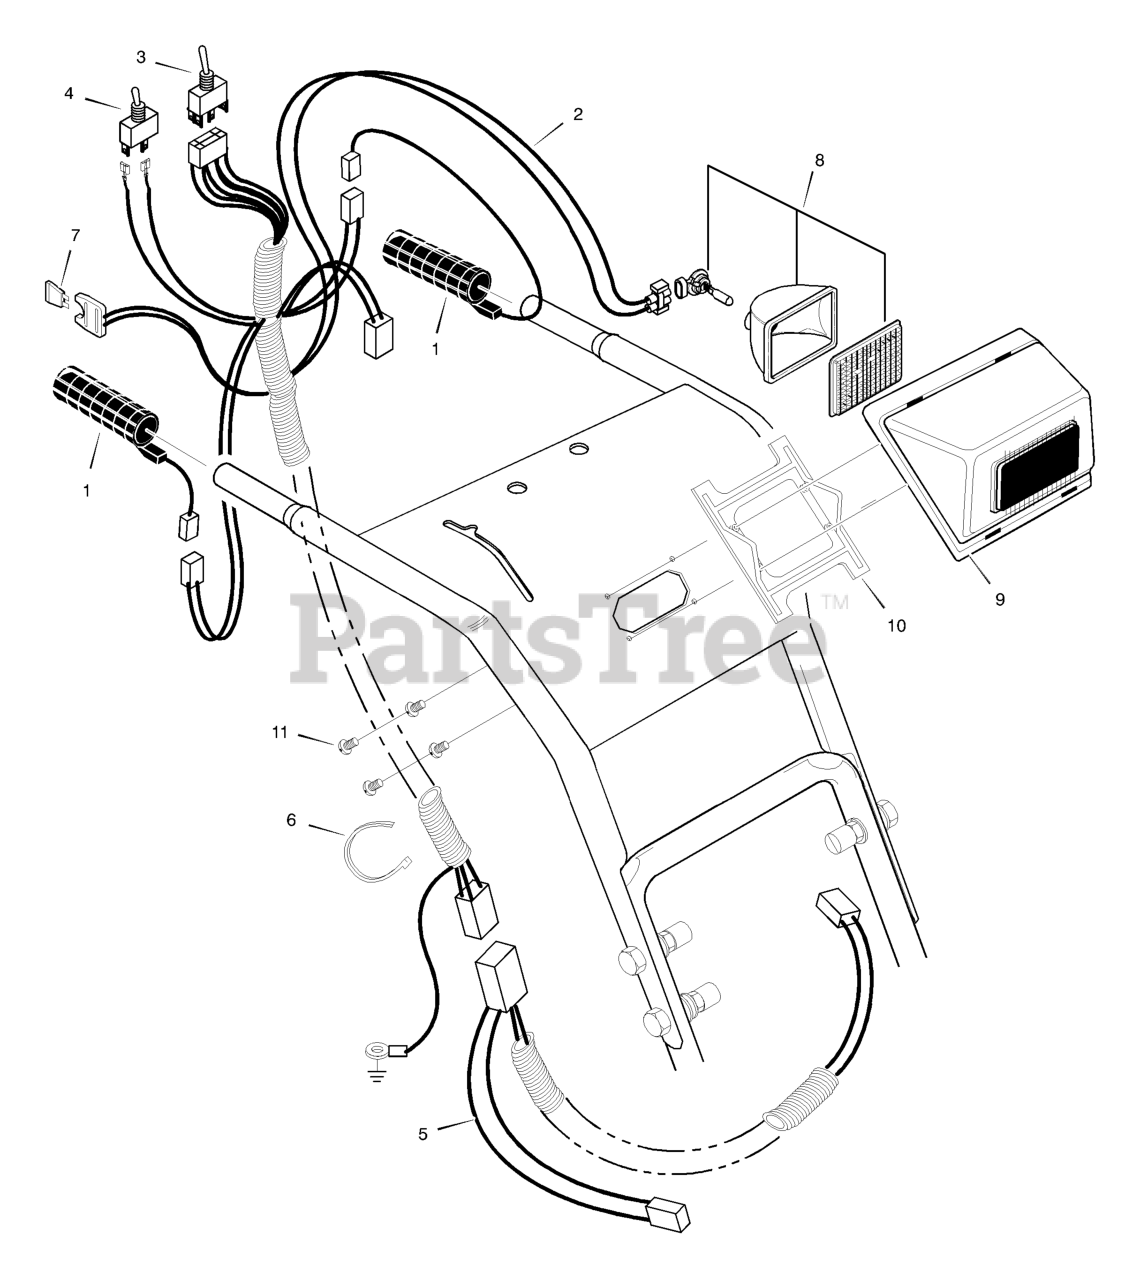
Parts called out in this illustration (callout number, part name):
1	GRIP, HEATED
2	WIRE, HARNESS
3	SWITCH, CHUTE ROTATION
4	SWITCH, HEATED GRIP
5	WIRE HARNESS, LOWER
6	TIE, CABLE
7	FUSE, 7.5 AMP AUTOMOTIVE
8	HEADLIGHT ASSEMBLY *
9	CASE, HEADLIGHT
10	BRACKET, HEADLIGHT
